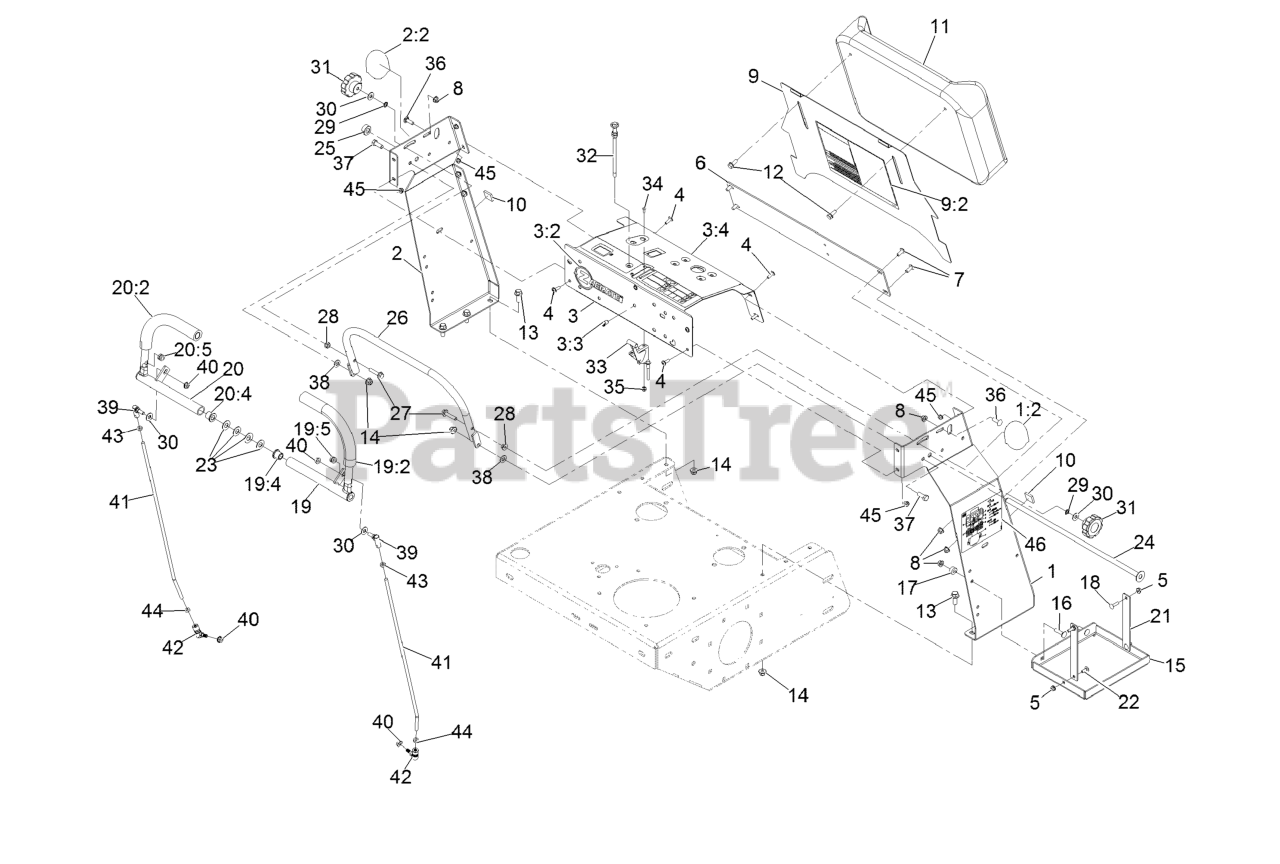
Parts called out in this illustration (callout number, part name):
1	PANEL-TOWER, LH
1:2	Decal-Z-Logo
2	PANEL-TOWER, RH
2:2	Decal-Z-Logo
3	PANEL-CONTROL
3:2	DECAL-Z-AERATE LOGO
3:3	Nut-Clinch, Hex
3:4	Decal-Control Panel
4	Screw-Hsbhf
6	PLATE-FACE
7	SCREW-PTH
8	NUT-HF, NI
9	PLATE-PAD,KNEE
9:2	Decal-Spray Chart
11	PAD-KNEE, Z-LOGO
12	SCREW-HHF
13	SCREW-HHF 3/8-16 X 1
14	NUT-HF, NI
15	TRAY-BATTERY
16	Bolt-Carriage 5/16-18 X 1 1/4
18	SCREW-CARR
19	HANDLE-CONTROL, LH ASM
19:2	GRIP-CONTROL, MOTION
19:4	BUSHING-FLANGE
19:5	Grommet-Rubber
20	HANDLE-CONTROL, RH ASM
20:2	GRIP-CONTROL, MOTION
20:4	BUSHING-FLANGE
20:5	Grommet-Rubber
21	Strap-Battery
22	BOLT-CARR
23	WASHER-PIVOT
24	Rod-Pivot, Joy Stick
26	Bar-Speed [red]
27	SCREW-HHF
28	Nut-Flange
29	Washer-Lock
30	FLAT WASHER, 5/16 NOM,ST
31	KNOB-FLUTED
32	CABLE-CHOKE
33	CABLE-THROTTLE
34	Screw-HSBH
35	Nut-Hex Flange
36	SCREW-CARR
37	SCREW-HH
38	WASHER-FLAT
39	Balljoint-SS
40	Nut-HHF
41	ROD-CONTROL
42	Ball Joint-Quick Disconnect, SS
43	Nut-Hex
44	Nut-Hex
45	Nut-Hex Flange
46	Decal-Service Aid
